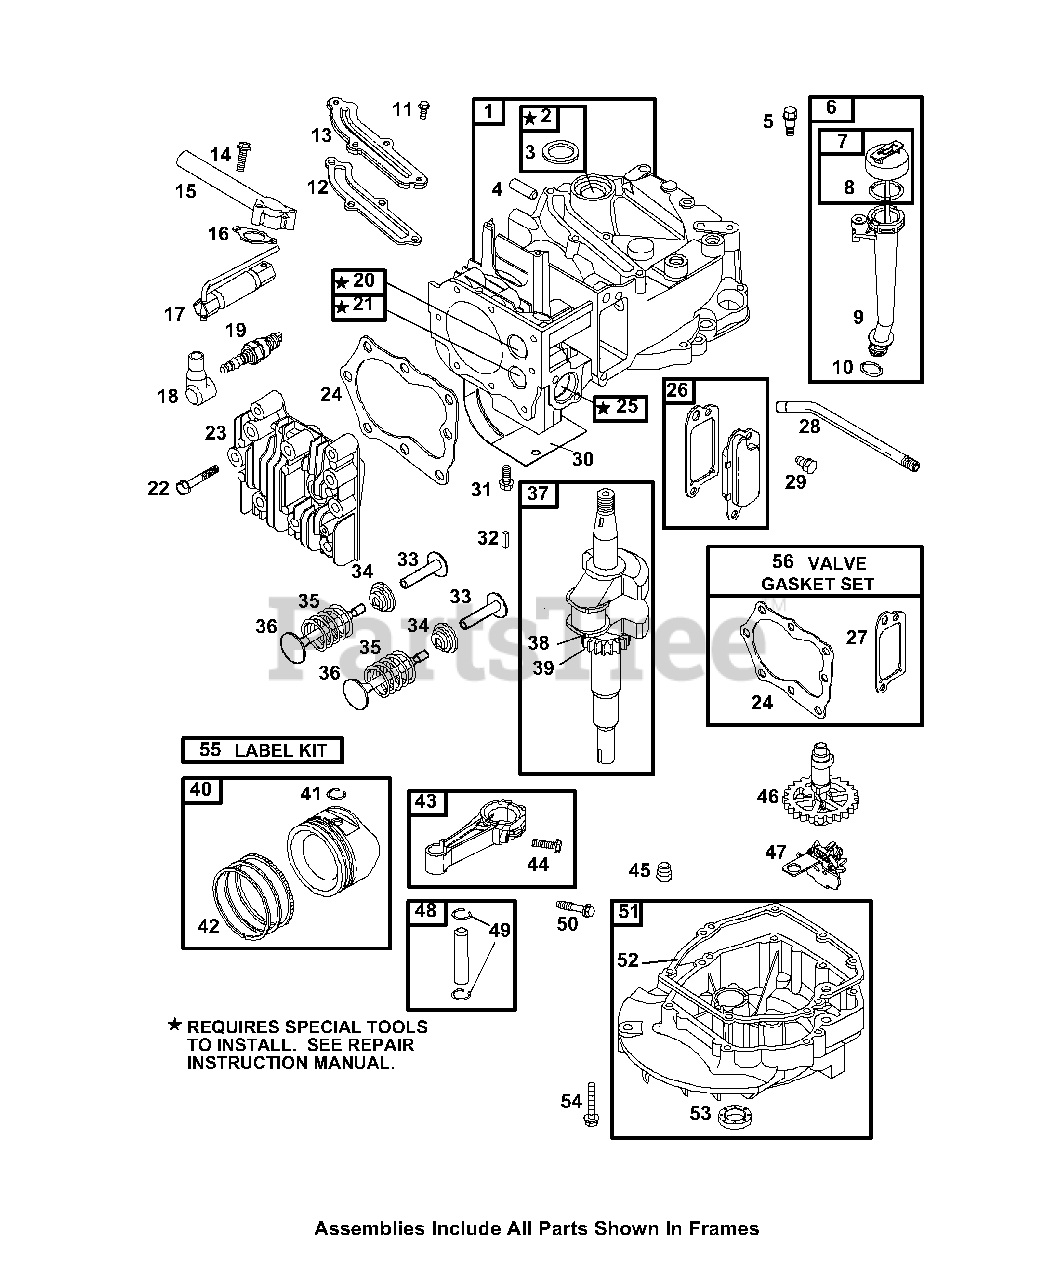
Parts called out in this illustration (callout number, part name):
1	Cylinder Head Gasket
2	Bushing/Seal Kit (Magneto Side)
3	Oil Seal (Magneto Side)
4	Locating Pin
5	Screw (Dipstick Tube)
6	Order Component Part
7	Dipstick
8	O-Ring Seal (Dipstick Tube)
9	Dipstick Tube
10	O-Ring Seal (Dipstick Tube)
11	Screw (Breather Passage Cover)
12	Breather Passage Cover
13	Breather Passage Gasket
14	Screw (Intake Manifold)
15	Intake Manifold
16	Intake Gasket
17	Spark Plug Wrench
18	Sparkplug Boot
19	Spark Plug
20	Valve Seat (Intake)
21	Valve Seat (Exhaust)
22	Screw (Cylinder Head)
23	Cylinder Head
24	Cylinder Head Gasket
25	Guide Bushing (Intake Valve)
26	Breather Assembly
27	Breather Gasket
28	Breather Tube
29	Screw (Breather Assembly)
30	Cylinder Shield
31	Screw (Cylinder Shield)
32	Flywheel Key
33	Valve Tappet
34	Valve Retainer
35	Valve Spring (Intake)
36	Intake Valve
37	Crankshaft
38	Timing Key
39	Timing Gear
40	Piston Assembly
41	Piston Pin Lock
42	Ring Set
43	Connecting Rod
44	Screw (Connecting Rod)
45	Oil Drain Plug
47	Governor/Oil Slinger
48	Piston Pin
49	Piston Pin Lock
50	Screw (Connecting Rod)
51	Engine Sump
52	Crankcase Gasket
53	Oil Seal
54	Screw (Engine Sump)
56	Valve Gasket Set
